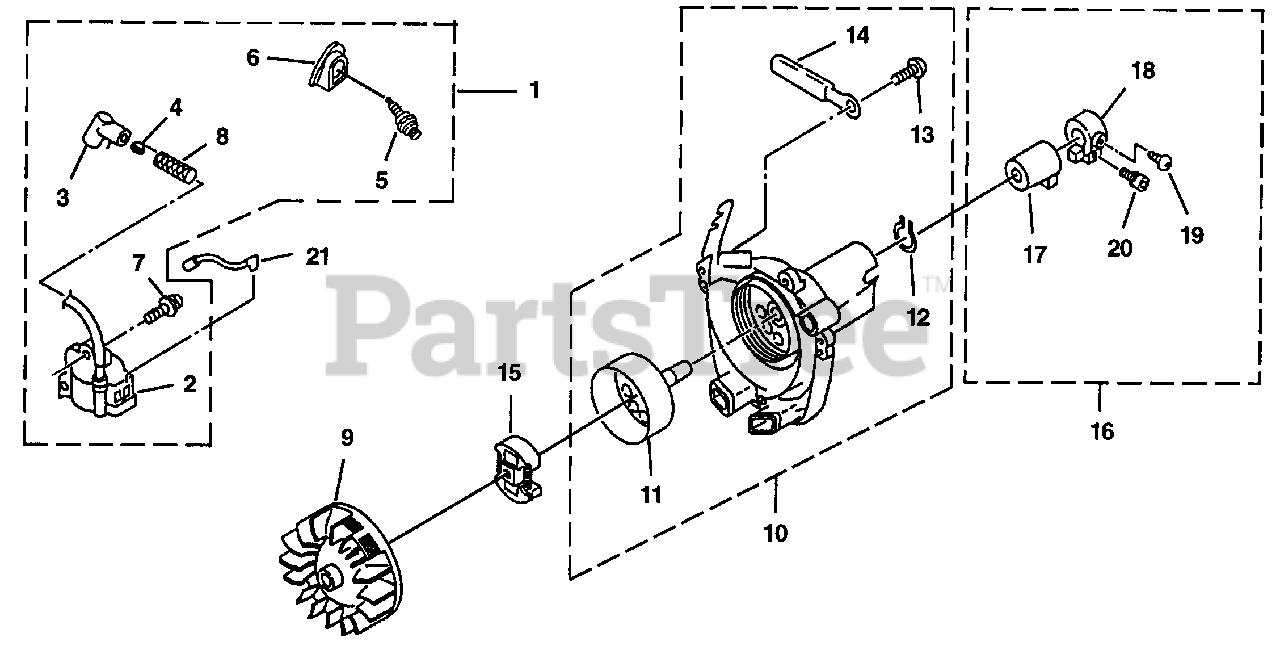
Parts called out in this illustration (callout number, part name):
1	IGNITION KIT
2	MODULE-Ignition
3	CAP-Plug
4	SPRING-Plug Cap
5	SPARK PLUG
6	COVER-Plug Cap
7	SCREW (M4 x 20 W SW)
10	CLUTCH HOUSING
11	CLUTCH DRUM
12	SNAP RING-Outer
13	SCREW-Self Tapping
14	CLAMP-Wire
16	DRIVESHAFT ISOLATOR
17	ISOLATOR
18	BRACKET-Isolator
19	SCREW-Self Tapping (M5 x 14)
20	SCREW-Socket Hd. (M5 x 25)
